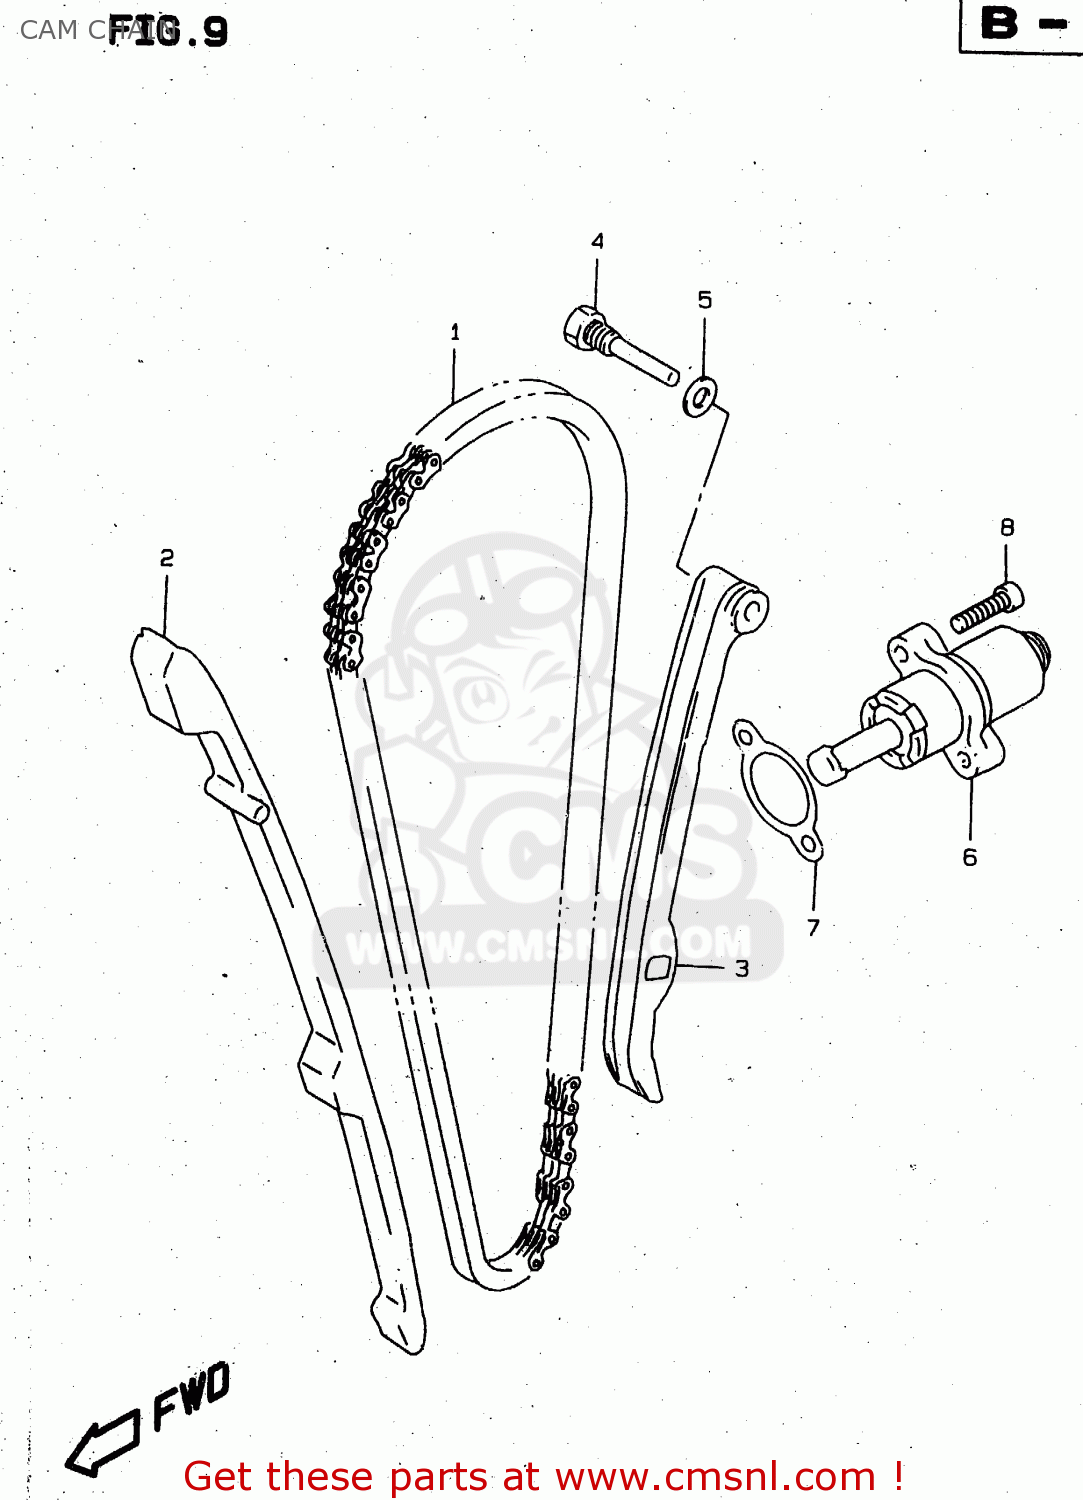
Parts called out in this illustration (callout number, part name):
1	CHAIN,CAMSHAFT DRIVE
2	GUIDE,CAM CHAIN
3	TENSIONER,CAM CHAIN
4	BOLT,CAM CHAIN TENSIONER
5	GASKET 8.2X14X1 (NAS)
6	ADJUSTER ASSY,TENSIONER
7	GASKET,TENSIONER ADJUSTER (NAS)
8	BOLT,CL.COVER
